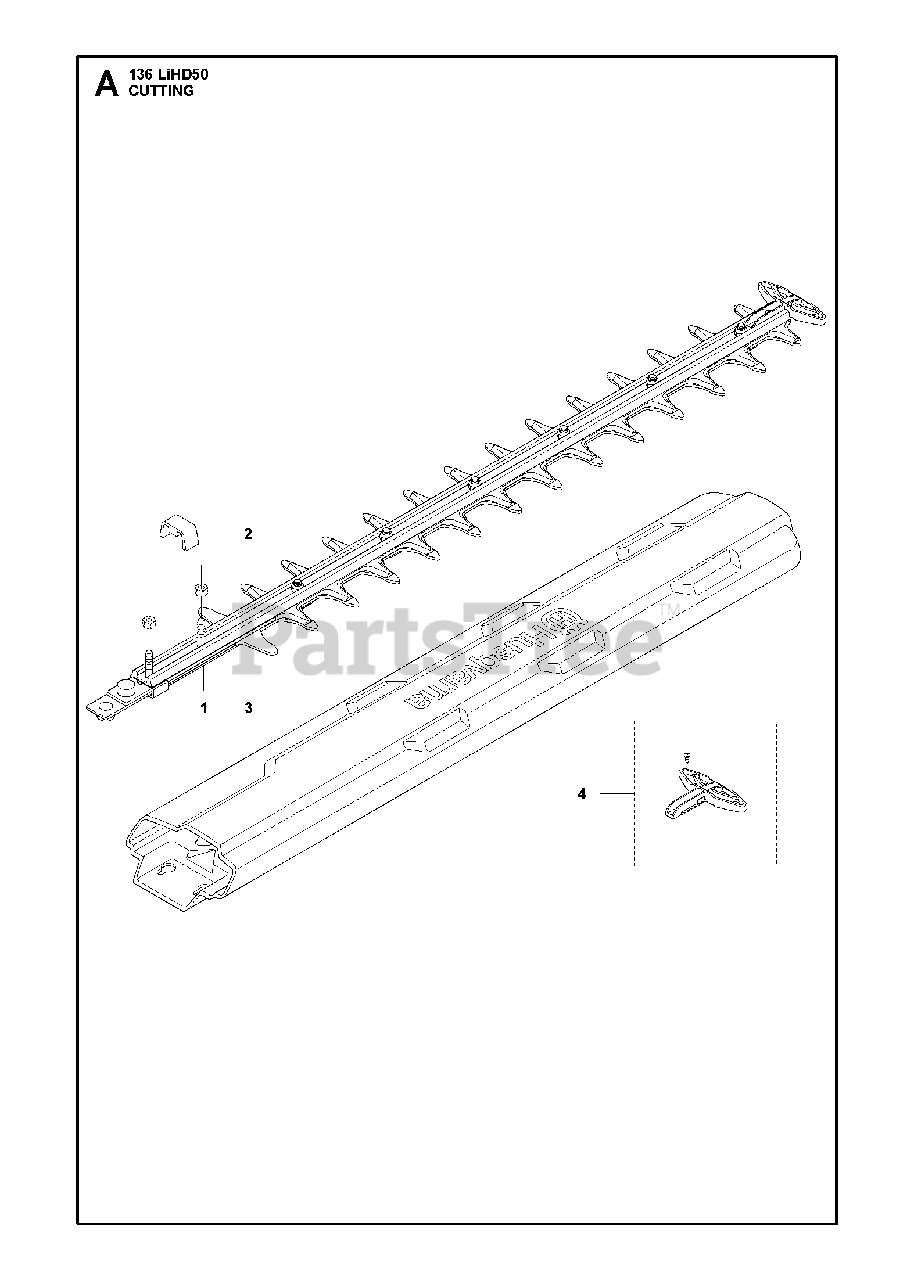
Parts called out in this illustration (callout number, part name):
1	BLADE ASSY
3	BLADE SHEATH
4	PROTECTION
